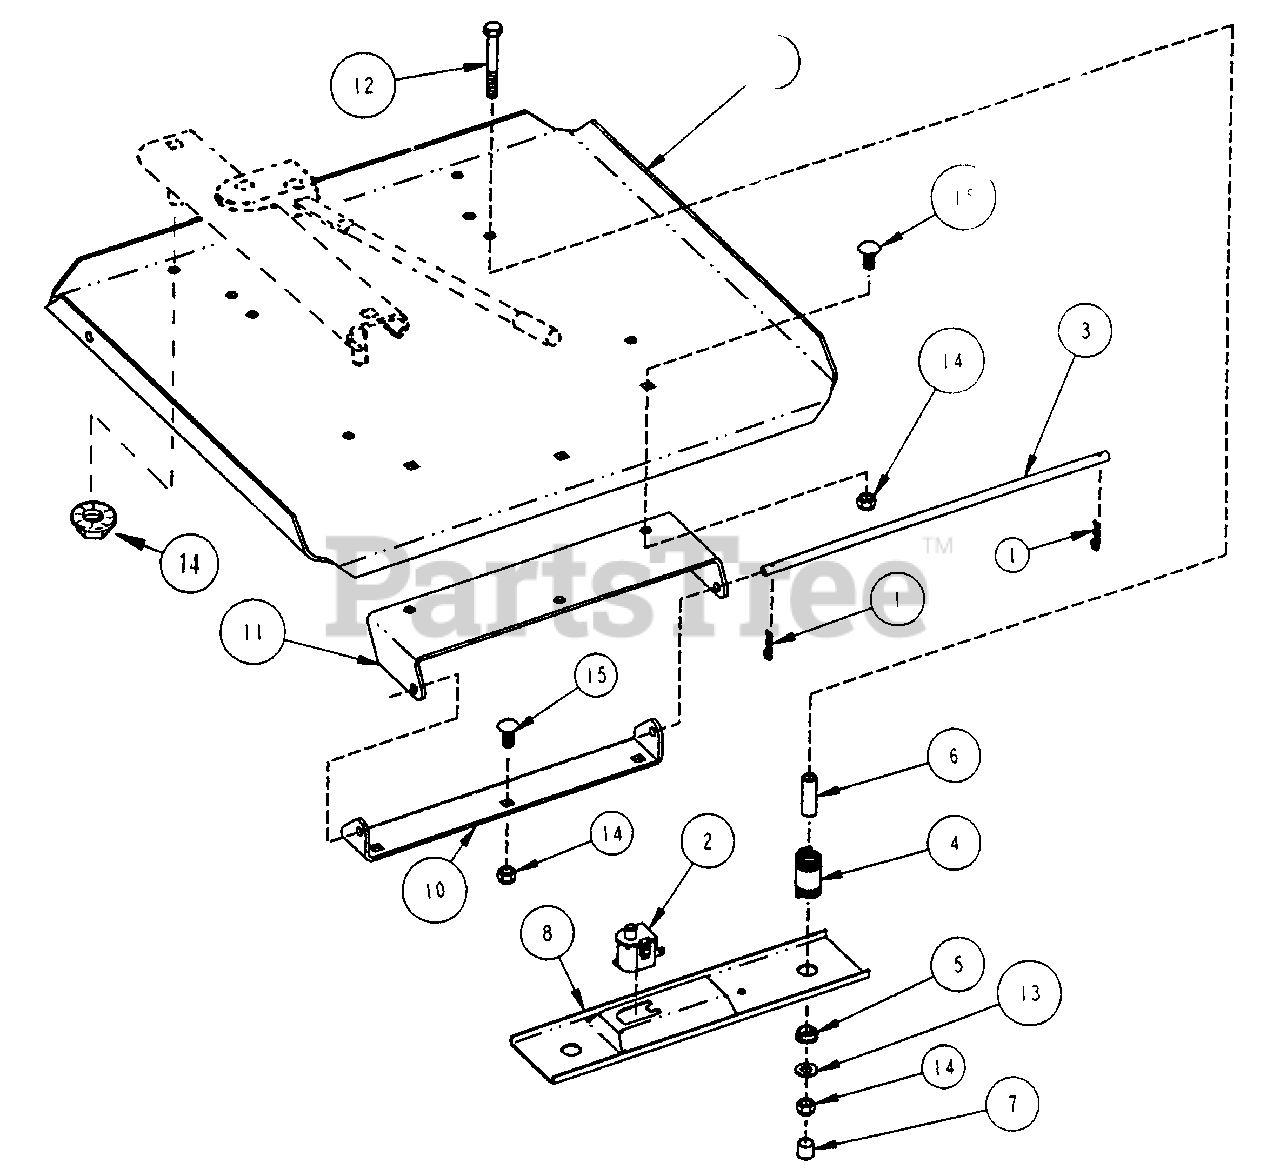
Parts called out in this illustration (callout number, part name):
1	HAIRPIN, 3/32 x 1-1/2
2	SWITCH, Seat (Normally Open)
3	ROD, 5/16 x 13" Long
4	SPRING, .106 Wire Dia, 68 I.D. x 1-1/2"
5	BUSHING, Molded Seat, 1/2 I.D., 5/8" O.D.
6	SPACER, .31 I.D., 1-3/8" Long
7	CAP, Vinyl, 1/4 I.D., 1/5 O.D.
8	HOLDER, Seat Switch
9	PLATE, Seat Support
10	BRACKET, Lower Seat Hinge
11	BRACKET, Upper Seat Support Hinge
12	BOLT, 5/16-18 X 2-1/2" GD5 YZ
13	WASHER, 5/16 x 11/16 O.D. Flat
14	NUT, 5/16-18 HEX NYLON LOCK
15	BOLT, 5/16-18 x 3/4 Short Sq. Nk. Carriage, Grade 5
